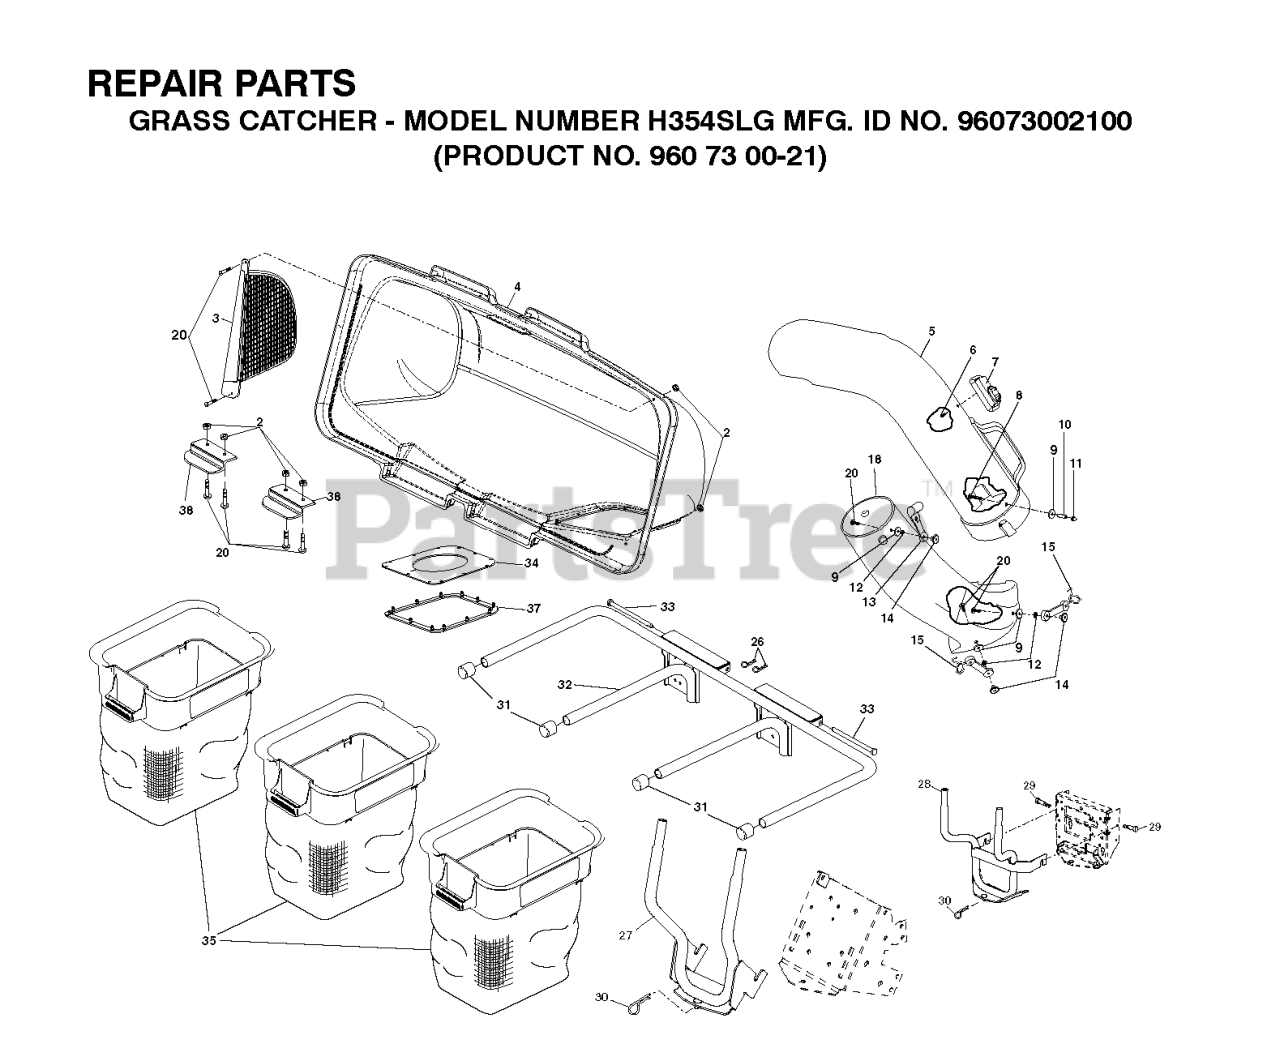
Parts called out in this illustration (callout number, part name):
3	SCREEN.COVER.BAGGER
4	COVER.ASM.3BIN.GENERIC.
5	UPPER CHUTE 54"
7	INDICATOR ASM BAG
8	SCREW
9	RP STEEL WASHER
11	NUT
12	LOCKWASHER #10
13	LATCH.HOOD.
14	WELDNUT
15	LATCH ASSY
18	CHUTE.BAGGER.LOWER.54"
20	SCREW
26	RETAINER SPRING
27	BAGGER.ASM.SUPPORT.GT.TEX.BLAC
28	BRACKET.BAGGER.3-BIN.BLACK
29	SHOULDER BOLT, SELF-TAP
30	SPRING.RETAINER.YELLOW.ZINC
31	PLUG, TUBING END
32	BAGGER.ASM.FRAME.3BIN.BLACK
33	BAGGER.HINGE.PIN
34	SEAL.BAGGER.TOP.3-BIN.BLK
35	CONTAINER BAG, SOFT
37	GASKET.COVER.BAGGER
38	LATCH CER38
